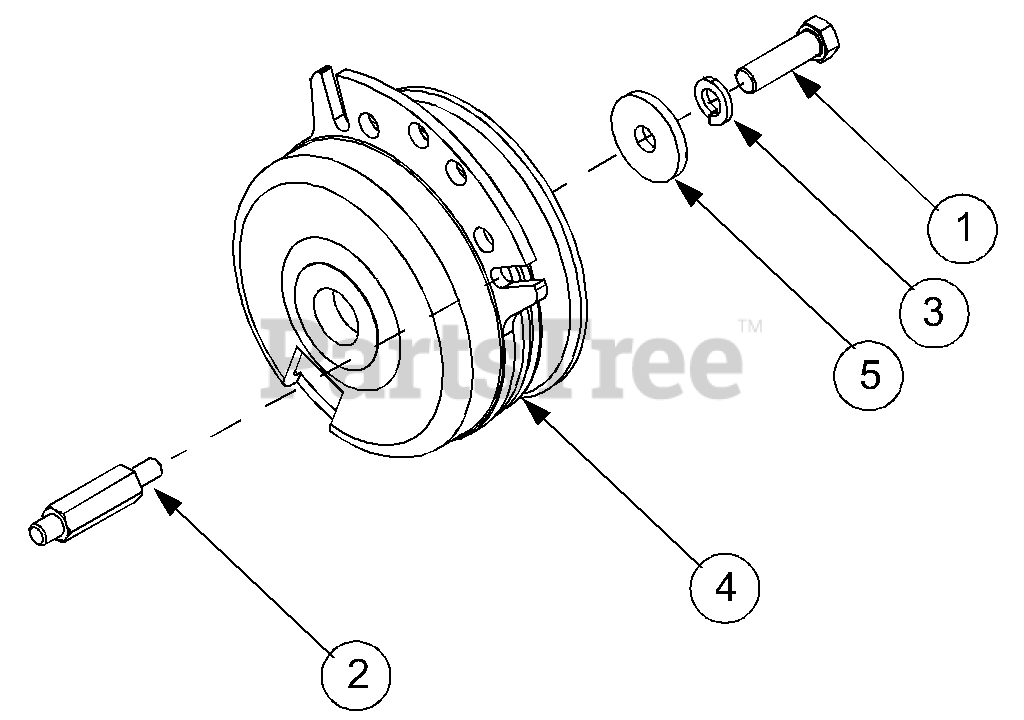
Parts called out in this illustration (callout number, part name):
1	Screw, Hex Cap, 3/8-24 x 1.5 GR8
2	Stud, Clutch Stop
3	Washer, Lock, 3/8
4	Clutch Assy, PTO
5	Washer, Flat, .445 x 1.5 x 1.72 Hdn
